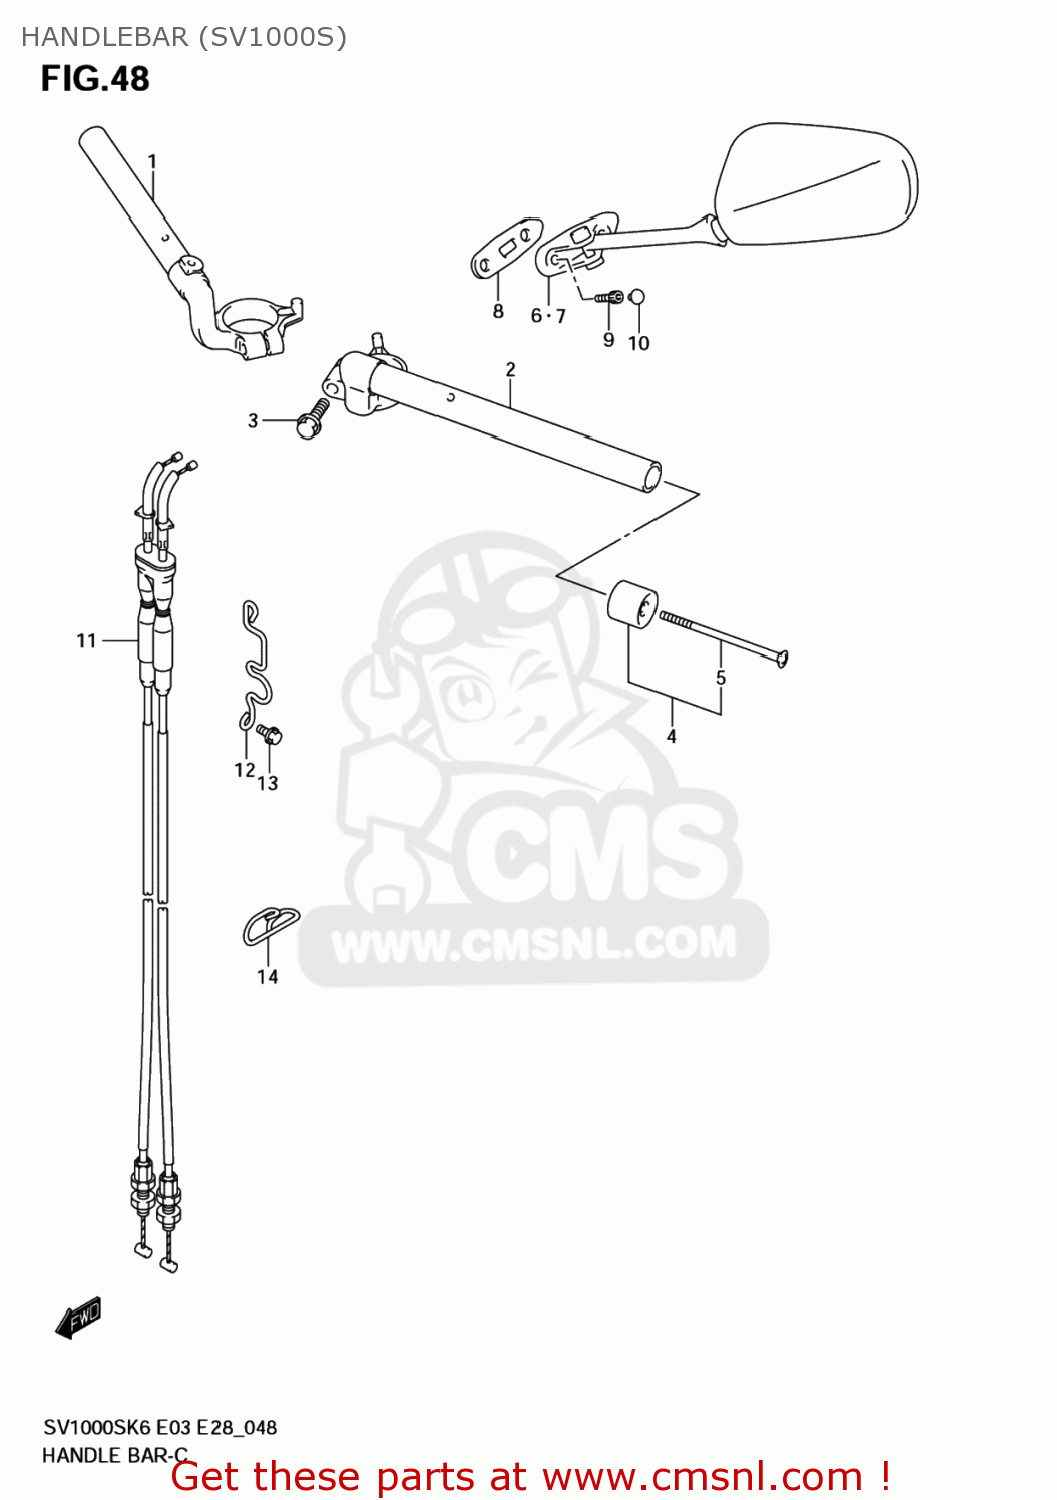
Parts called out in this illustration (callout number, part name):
1	HANDLEBAR,R
2	HANDLEBAR,L
3	BOLT,HANDLEBAR
4	BALANCER SET,HANDLEBAR
5	SCREW
6	MIRROR ASSY,RR VIEW,R
7	MIRROR ASSY,RR VIEW,L
8	CUSHION,RR VIEW MIRRORR
9	BOLT
10	CAP(OD:10)
11	CABLE ASSY,THROTTLE
12	GUIDE,CABLE L
13	BOLT
14	GUIDE,THROTTLE CABLE
